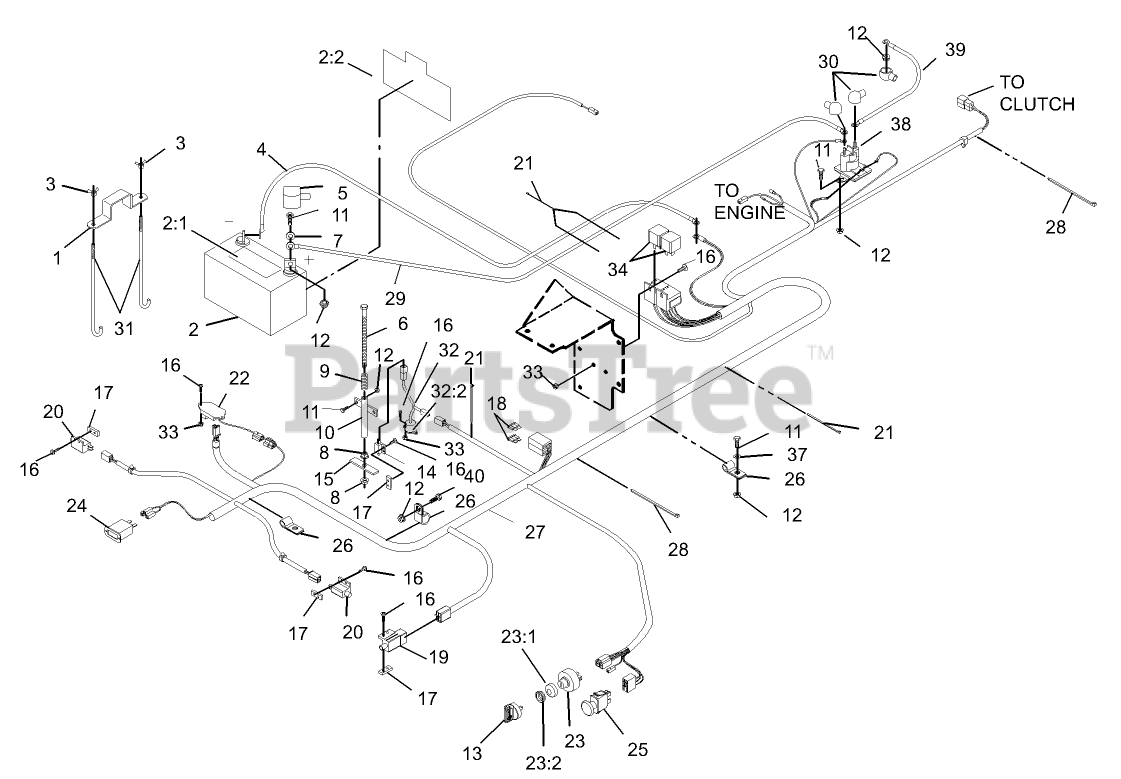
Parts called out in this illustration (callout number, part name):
1	STRAP-HOLDDOWN
2	BATTERY
2:1	Decal-Battery
2:2	Decal-Battery
3	WINGNUT
4	WIRE-GROUND
5	INSULATOR-BATTERY
6	SCREW-HH
7	WASHER-FLAT
8	NUT-HF
9	SPRING-SWITCH, SEAT
10	MOUNT-SPRING, SEAT
11	SCREW-HH
12	NUT-HF
13	KEY-IGNITION
14	SWITCH-CLOSED, NORMALLY
15	PLATE-SWITCH, SEAT
16	SCREW-PPH
17	PLATE-TAPPED
18	FUSE-BLADE TYPE, 20 AMP
19	SWITCH
20	SWITCH-OPEN, NORMALLY
21	TIE-CABLE
22	MODULE-DELAY, SEAT
23	Key Switch ASM
23:1	WASHER-TOOTH, INTERNAL
23:2	NUT-HH
24	METER-HOUR
25	SWITCH-DELTA
26	CLIP-LOOM
27	Harness-Wire
28	TIE-PLASTIC
29	WIRE-STARTER
30	INSULATOR-SOLENOID
31	BOLT-HOLDDOWN
32	TILT SWITCH ASM
32:2	DECAL-SWITCH, MERCURY
33	NUT-LOCK, NI
37	WASHER-FLAT
38	SWITCH-SOLENOID
39	CABLE-STARTER, POSITIVE
40	SCREW-HH
